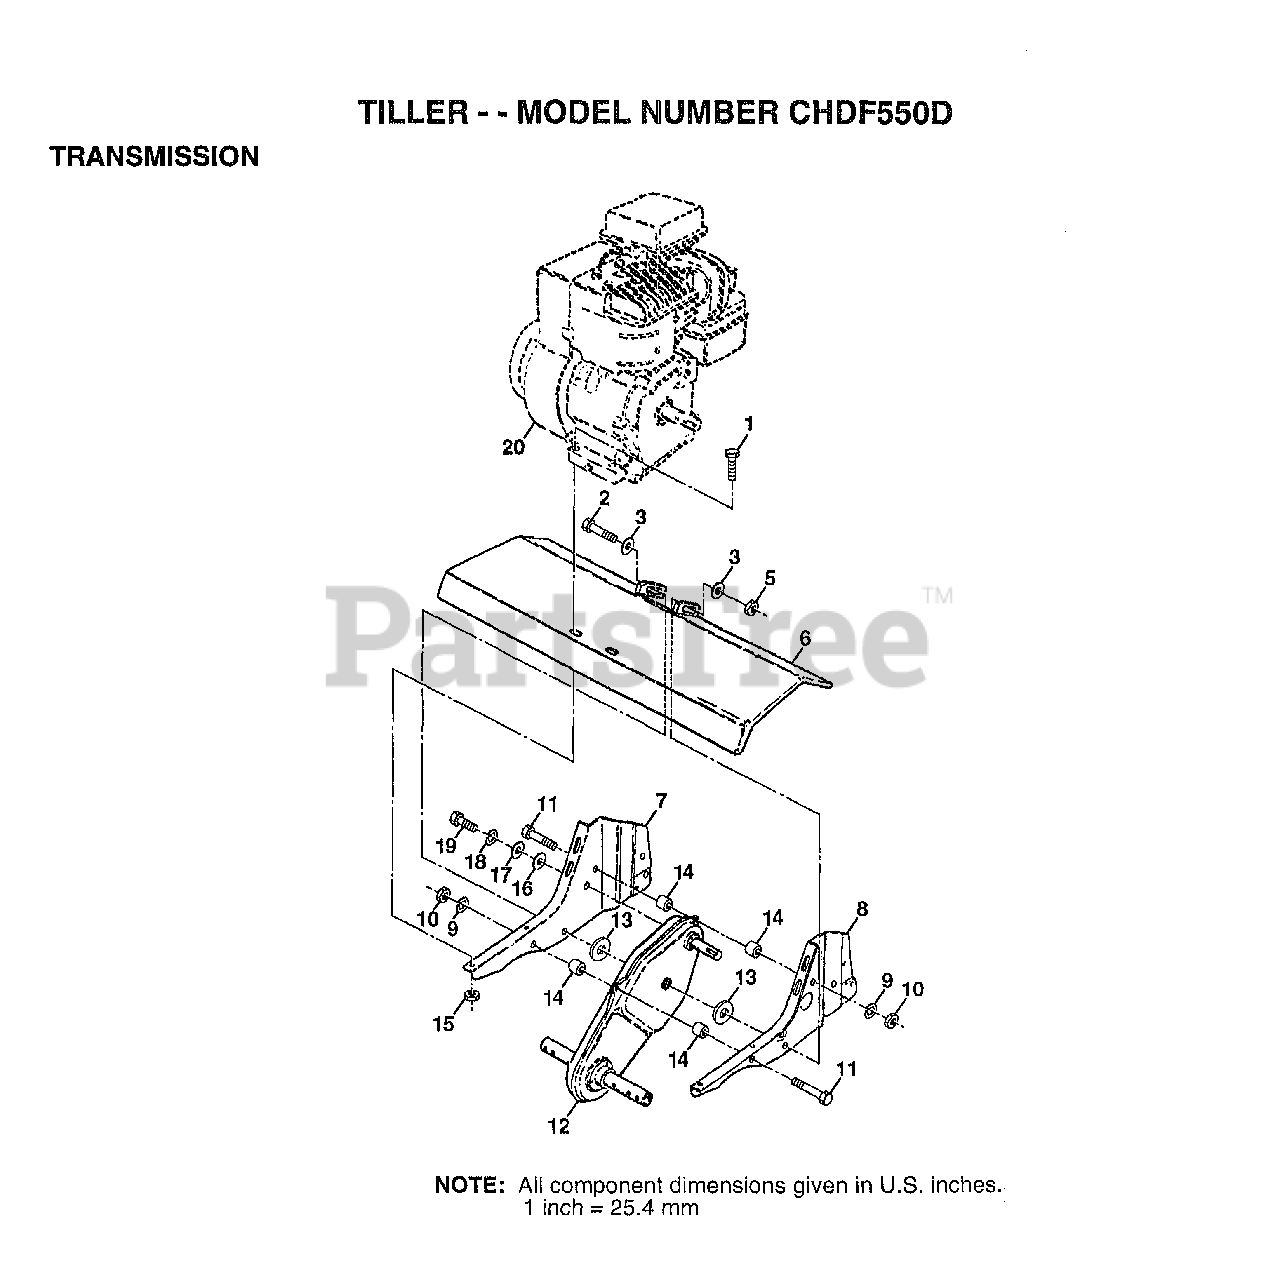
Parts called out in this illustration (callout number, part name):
1	BOLT.HEX.5/16-1.5
2	BOLT HEX 3/8-16
3	WASHER
5	NUT
6	SHIELD TINE
8	ENGINE BRKT LH TI
9	LOCKWASHER
10	NUT.HEX.5/16-18
14	SPLIT SPACER RT
16	WASHER
17	WASHER
18	LOCKWASHER
19	BOLT
